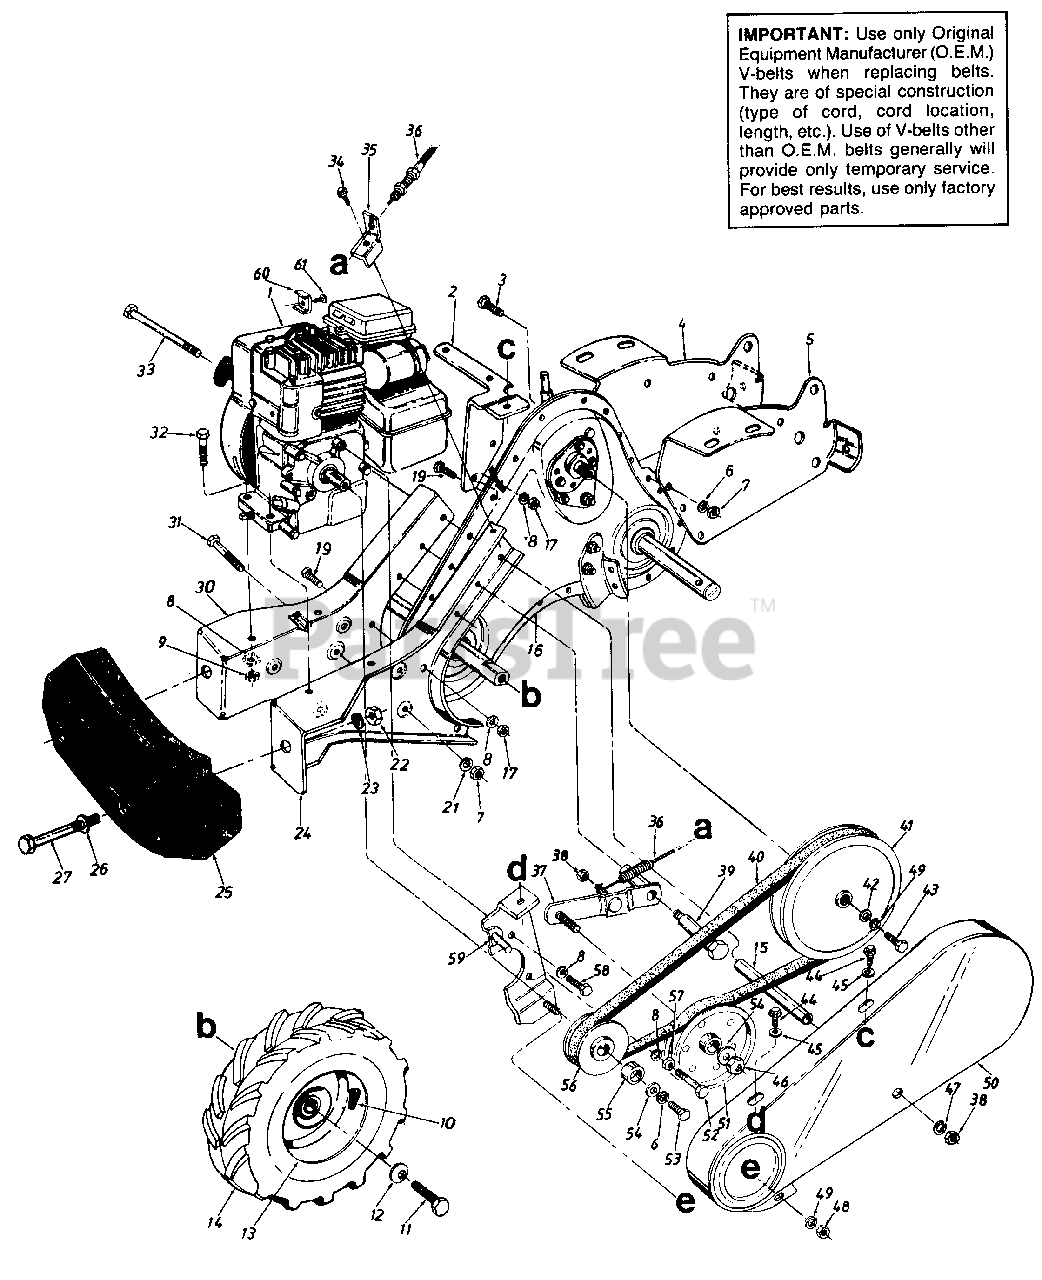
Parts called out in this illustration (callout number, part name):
1	Engine
7	Hex Nut 3/8-16 Thd.
8	L-Wash. 5/16" I.D.
9	Hex Nut 5/16-18" Thd.
10	Air Valve
11	Hex Bolt 5/16-24 x .62" Lg.
12	Bell-Wash. .345" I.D. x .88"
13	Wheel Rim Ass'y. Only
14	L.H. Wheel Ass'y. Comp.
16	Transmission Comp.
17	Hex Nut 5/16-18 Thd.
19	Hex Bolt 5/16-18 x .75" Lg.
21	L-Wash. 3/8" I.D. H.D.
22	Hex Nut 1/2-13 Thd.
23	L-Wash. 1/2" I.D.
26	Fl-Wash. .510" I.D. x 1.0"
27	Hex Bolt 1/2-13 x 5.00" Lg.
32	Hex Bolt 5/16-18 x 1.50"
33	Hex Bolt 5/16-18 x 4.75" Lg. Grade 2
34	Hex Wash. TT-Tap Scr. 5/16-18 x .62" Lg.
35	Bracket Clutch Cable
36	Clutch Control Cable 53" Lg.
39	Shld. Bolt 500" Dia. x 2.27"
40	"V"-Belt
41	"V"-Pulley Split 5/8" I.D.
42	Fl-Wash. 1/4" I.D. x .93" O.D.
43	Hex Bolt 1/4-28 x .75" Lg.
44	Hex Wash. Hd. S-Tap Scr. 1/4-20 x .50" Lg.
45	Fl-Wash. .281" I.D. x .625n
46	Hex Cent. L-Nut 3/8-24 Thd.
47	Fl-Wash. 5/16" I.D.
48	Hex Nut 1/4-20 Thd.
49	L-Wash. 1/4" I.D.*
51	Fl-ldler w/Flanges 3.75" O.D.
52	Hex Bolt 5/16-24 x 1.75"
53	Hex Bolt 3/8-24 x 1 00" Lg.
54	Fl-Wash. 3/8" I.D. x 1.00"
55	Spacer 758" I.D. x .990"
56	Engine Pulley
57	Hex Nut 5/16-24 Thd.*
58	Hex Bolt 5/16-24 x .62" Lg.
61	Hex Sems Scr. #10-32 x .62"
